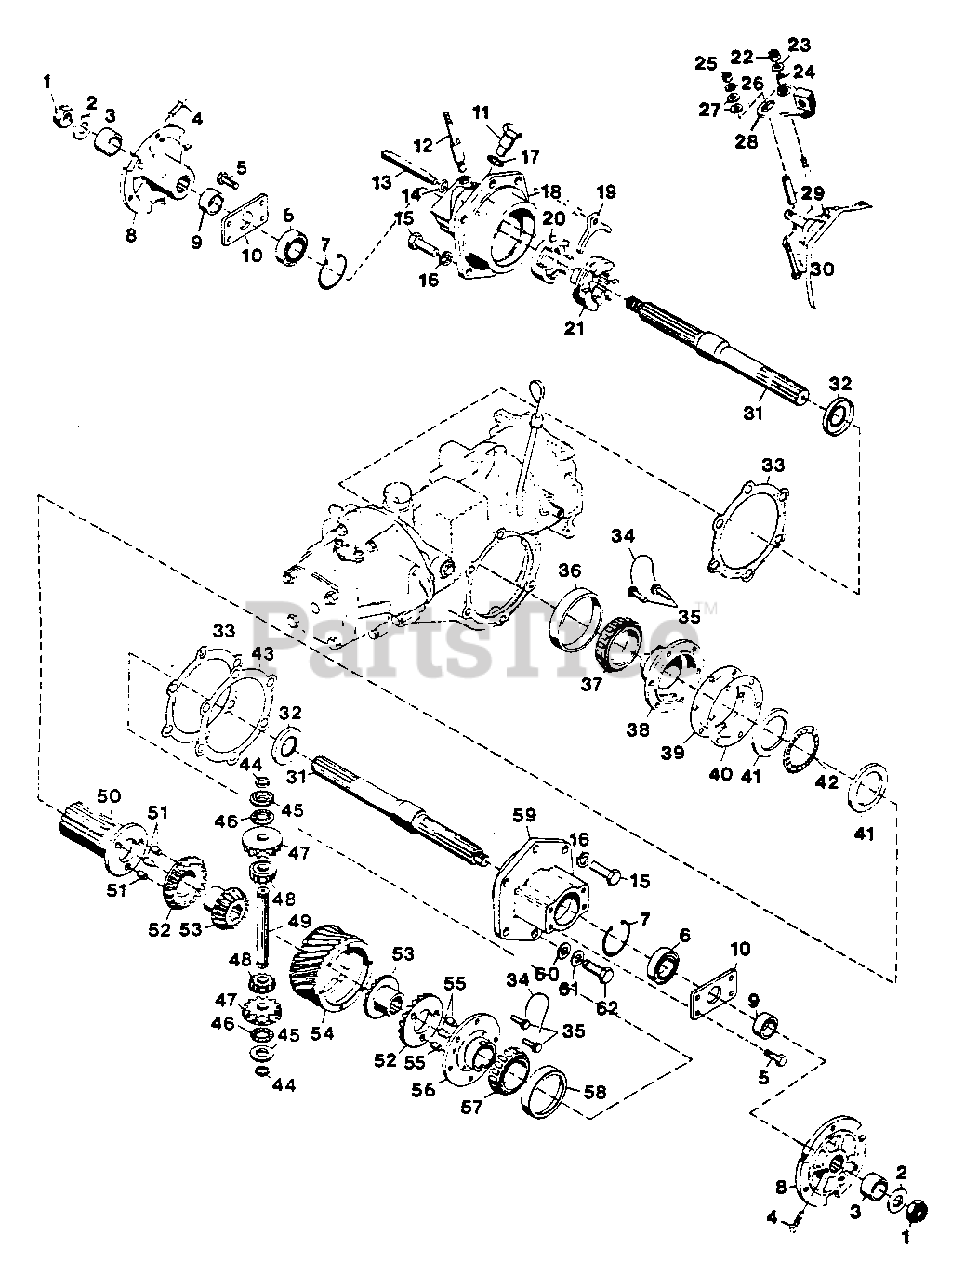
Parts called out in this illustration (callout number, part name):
1	Nut, Hex 3/4-10 Light Thin
2	Washer, Flat .812x1.469x.134
3	Spacer
4	Screw, Set 7/16-14x1.0 SCP
5	Bolt, Hex 3/8-16x.750
6	Bearing, Ball 1.000x2.000x.562
7	Ring, Retaining 2.000 Bore
8	Hub, Wheel
9	Spacer
10	Plate, End
11	Bolt, Stationary Clutch
12	Pivot, Stationary
13	Pin, Clutch Sliding
14	O-Ring, .438x.625x.094
15	Bolt, Hex 1/2-13x1.00
16	Washer, Lock 1/2 Reg.
17	Washer, Oil Strainer Nut
18	Housing. Axle 2-Speed
19	Yoke, Shifting
20	Clutch, Stationary
21	Clutch, Shifting
22	Nut, Lock 5/16-18
23	Washer,Flat .344x.688x.065
24	Bushing, Nylon .375x.503x.875
25	Nut, Lock 1/4-20
26	Washer, Flat .281x.625x.065
27	Washer, Flat .406x.812x.065
28	Weldment, Arm Shifter
29	Bushing
30	Bolt, 1/4-20x2.25 Gr. 8 PHD
31	Axle, Straight
32	Seal, Oil 1.188x2.000x.250
33	Gasket, Axle Housing
35	Bolt, Special 5/16-18
36	Cup, Roller Bearing
37	Cone, Roller Bearing
38	Housing, Clutch
39	Shim, Worm Gear .020
40	Shim, Worm Gear .005
41	Race, Thrust 2.00x2.740x.031
42	Bearing, Needle Thrust .050
43	Shim, Axle Housing .005
44	Ring, Retaining .750 Shaft
45	Spacer, .765x1.245x.200
46	Brg, Needle Thst .752x1.240x.078
47	Gear, Diff. Shifting Bevel
48	Gear, Spider Bevel
49	Pin, Spider
50	Shifter, Splined Pinned
51	Pin, Dowel .375x.375
52	Gear, Pinned Bevel
53	Gear, Differential Bevel
54	Gear, Worm 8 Start
55	Pin, Dowel .375x.500
56	Housing, Pinned
57	Cone, Roller Bearing
58	Cup, Roller Bearing
59	Housing, Axle
60	Seal, Oil Drain
61	Washer, Flat .531x1.062x.095
62	Bolt, Hex 1/2-13x1.00 Nylon Ins.
